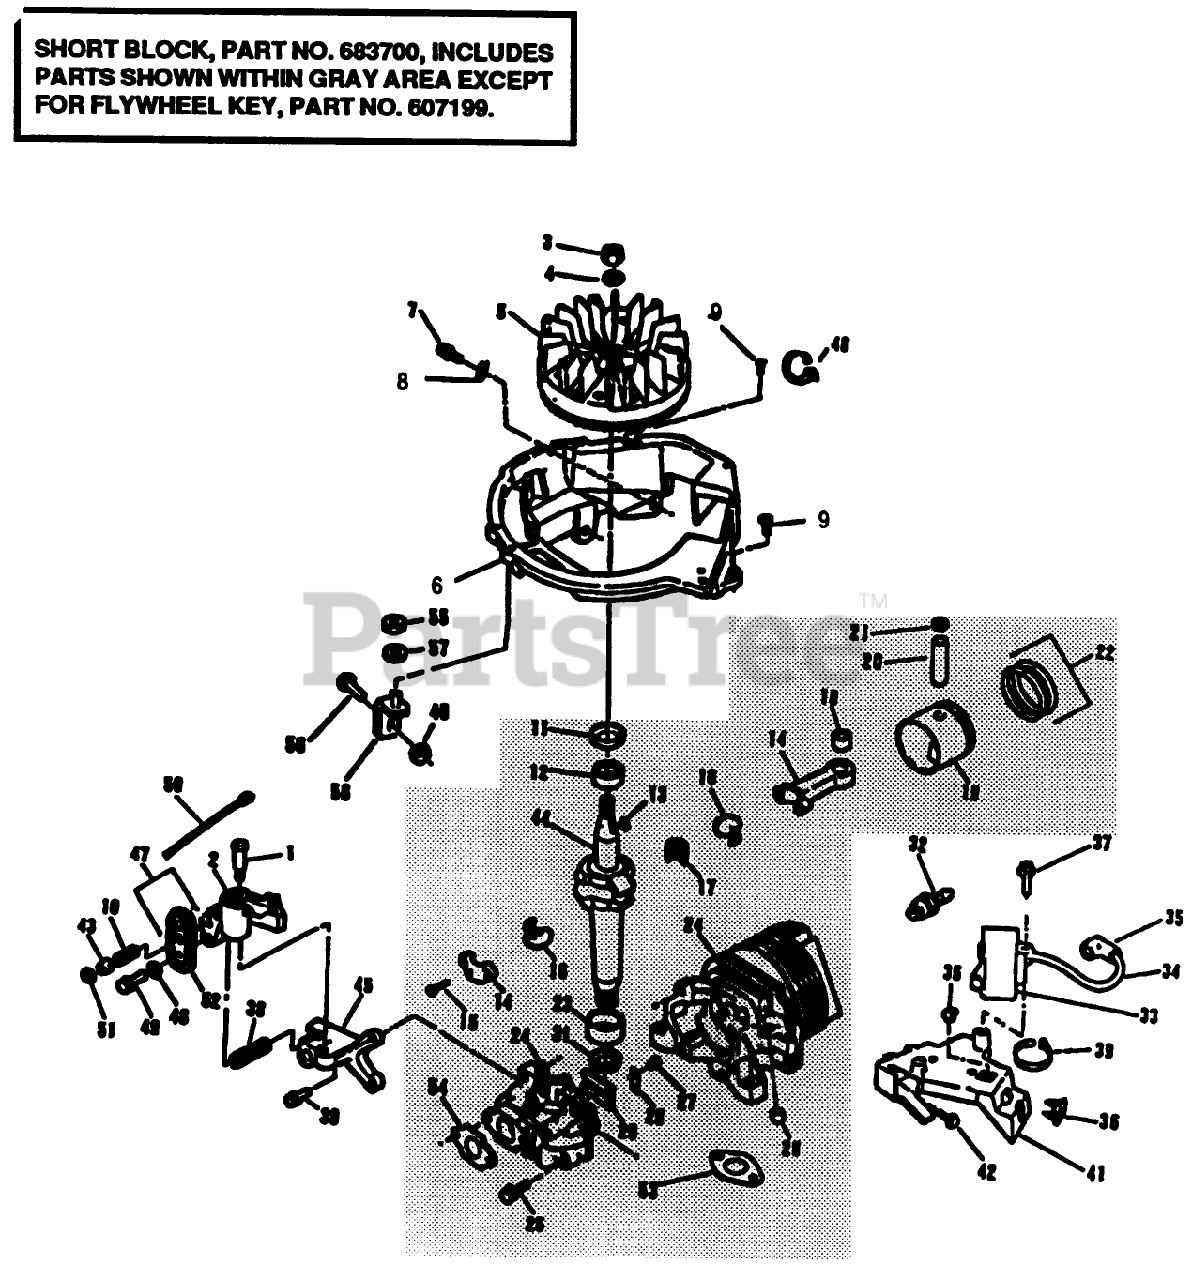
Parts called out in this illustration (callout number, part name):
1	SCREW-SHOULDER
3	NUT
5	FLYWHEEL ASSY F
6	BASE SHROUD F
7	SCREW-SEMS
9	SCREW F
10	SPRING
11	SEAL-OIL
12	BEARING V
13	KEY
15	SCREW-HSH
16	LINER ASM
17	BEARING-NEEDLE
18	BEARING AY F
21	RING-RETAINING
23	BEARING V
25	SCREW-H.W.HD. F
26	PLUG-CORE VF
27	SCREW-HH
28	PLATE-BACKUP, REED
30	SCREW
31	SEAL-OIL
32	SPARK PLUG
34	HT LEAD&COVER XEV
36	NUT-CLIP
38	SPRING-BRAKE
39	TIE-CABLE
40	NUT-LOCK F
41	C.D. BRKT F
42	SCREW F
43	ACTUATOR-LEVER, BRAKE
45	BRACKET-BRAKE F
50	WIRE LEAD AY F
51	RETAINER S
54	GASKET CARB S
55	LOCKNUT E
56	BOLT F
58	BRACE AY F
